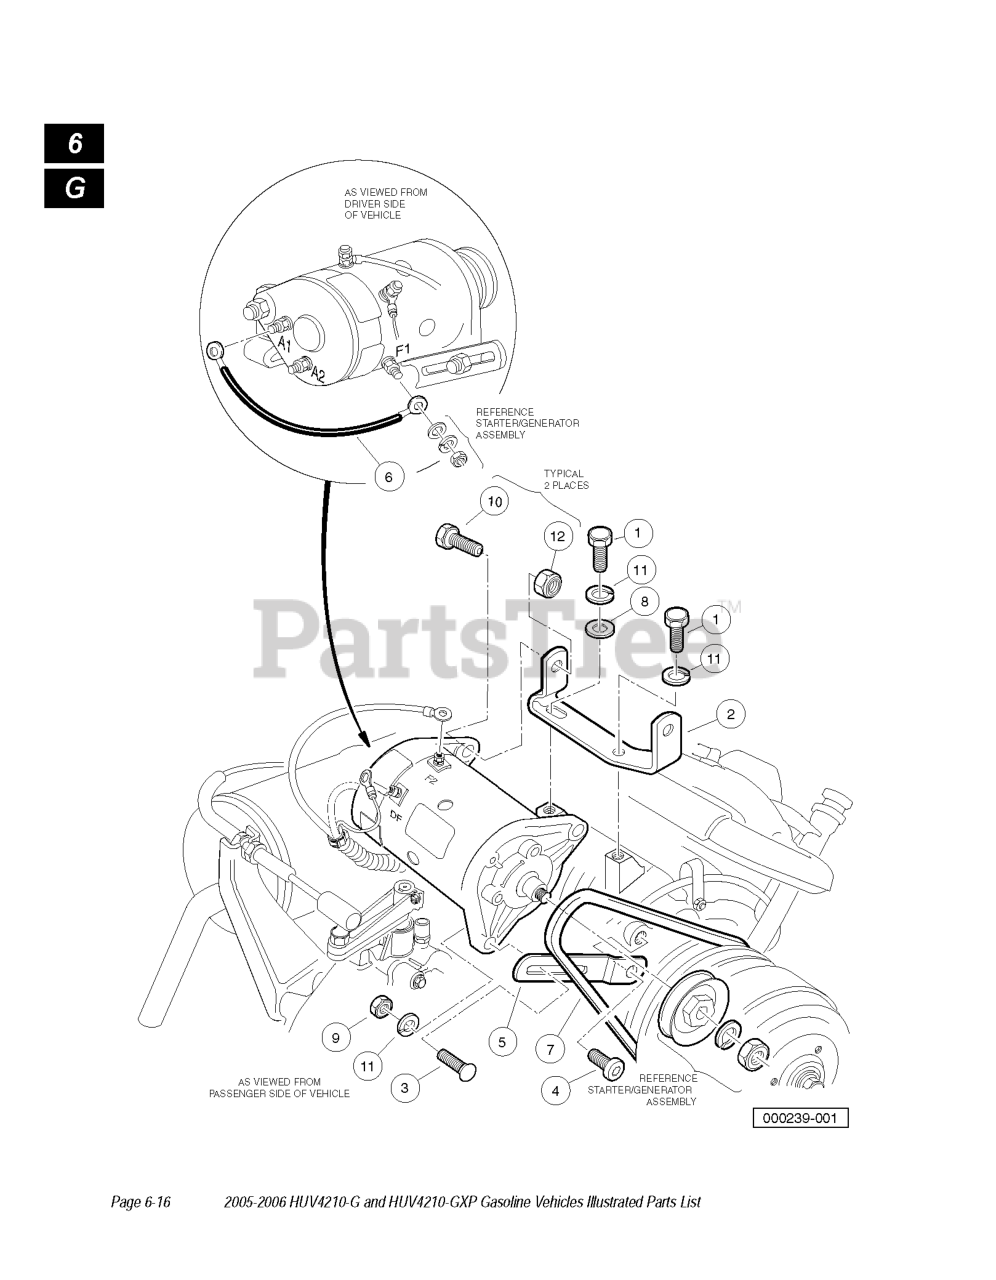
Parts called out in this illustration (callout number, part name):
1	SCREW, M8-125 X 22 HEX GR.8.8
2	BRACKET, FE350 S/G MOUNTING
3	BOLT, 5/16-18 RD HD SQ NECK
4	SCREW, M8-1.25 X 18MM TORX
5	BRACKET, S/G-ADJUSTABLE
6	WIRE ASSY, #6 GREEN
7	BELT, STARTER-GENERATOR
8	WASHER, 5/16 TYPE A FLAT
9	NUT, 5/16-18 HEX
11	LOCKWASHER, 5/16 SPLIT
12	LOCKNUT, 3/8-16 HEX
